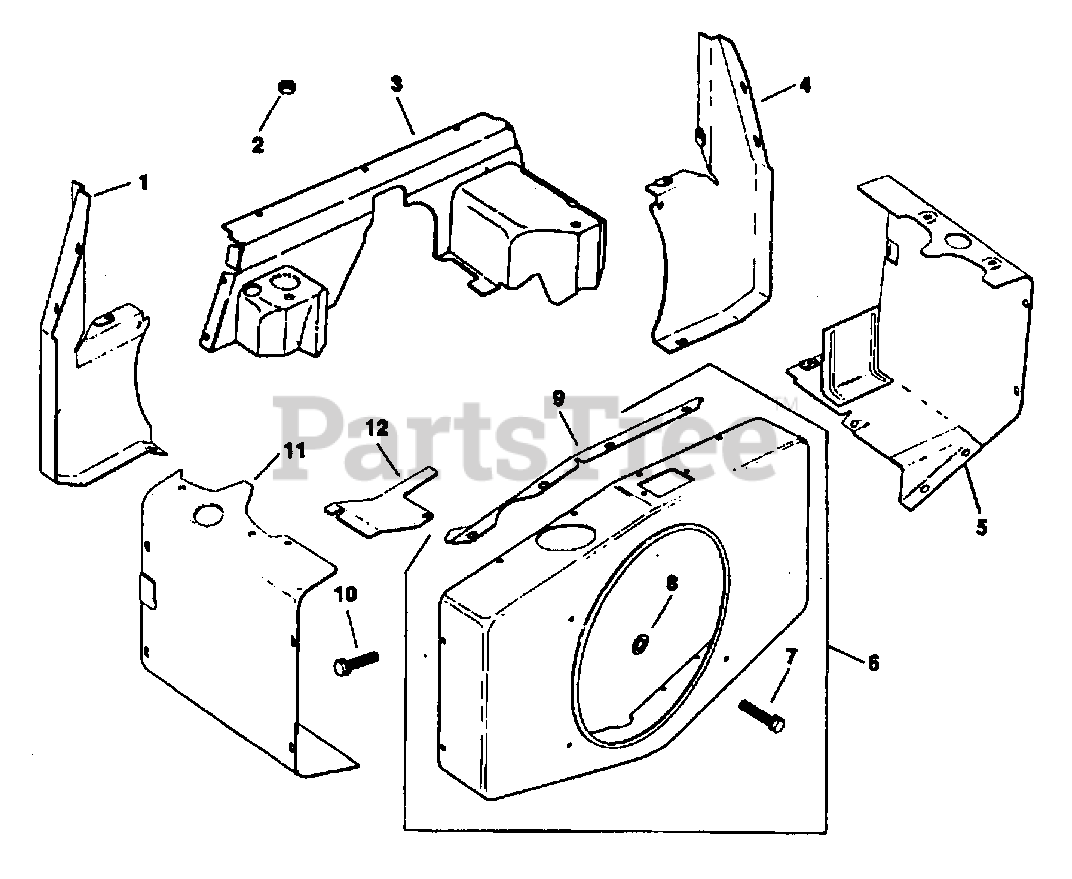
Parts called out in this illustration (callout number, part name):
1	DUCT, AIR
2	NUT
3	COVER, AIR DUCT
4	DUCT, AIR
5	BAFFLE
6	KIT, BLOWER HOUSING
7	SCREW
8	WASHER
9	SUPPORT, UPPER HOUSING
10	SCREW
11	BAFFLE
12	BAFFLE
